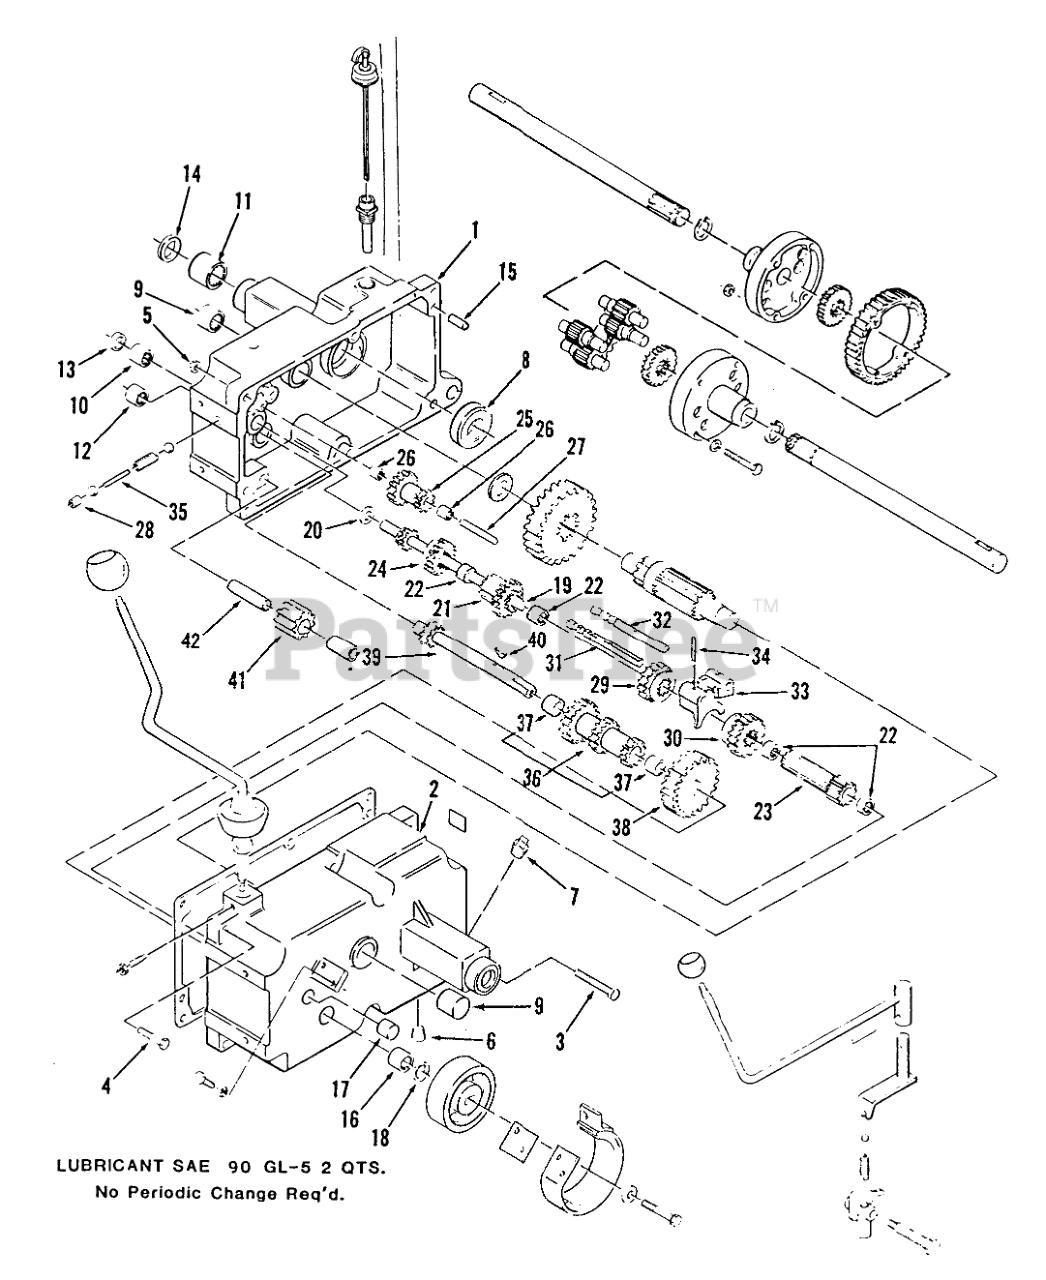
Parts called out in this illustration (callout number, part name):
1	CASE TRANS RH
2	CASE TRANS LH
3	HHCS
4	Bolt
5	Nut
6	PLUG 1/4 PIPE ALLEN
7	Plug
8	BEARING-BALL
9	BEARING-NEEDLE
10	BEARING-NEEDLE
11	BEARING-NEEDLE
12	BEARING-NEEDLE
13	SEAL-OIL
14	OIL SEAL
15	PIN-DOWEL
16	BEARING-NEEDLE
17	Bearing Needle
18	SEAL-OIL
19	SHAFT-INPUT
20	WASHER-THR
21	GEAR
22	BEARING-NEEDLE
23	GEAR
24	GEAR-SLIDING
25	Gear
26	BEARING-NEEDLE
27	GEAR-SHAFT REDUCTION
28	CUP-PLUG
29	GEAR-HI AND 2ND
30	GEAR-LOW AND REVERSE
31	RAIL-SHIFT
32	RAIL-REAR SHIFT
33	FORK-SHIFT
34	PIN-ROLL
35	PIN-SHIFT
